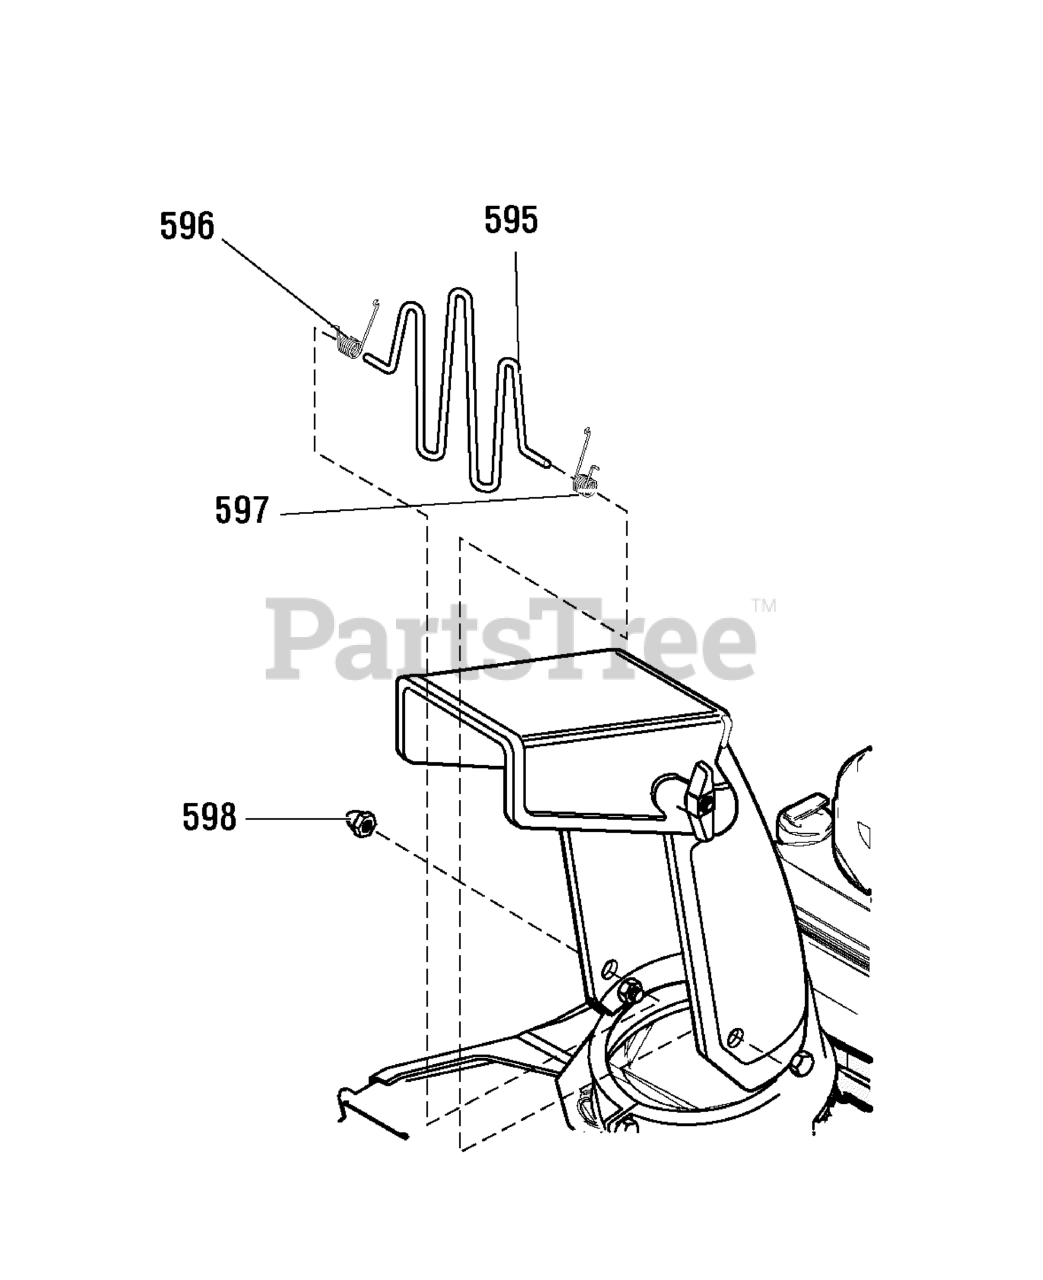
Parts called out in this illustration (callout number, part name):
595	Guard, Wire Chute
596	Spring, Torsion Chute
597	Spring, Torsion Chute
598	Nut, Acorn
